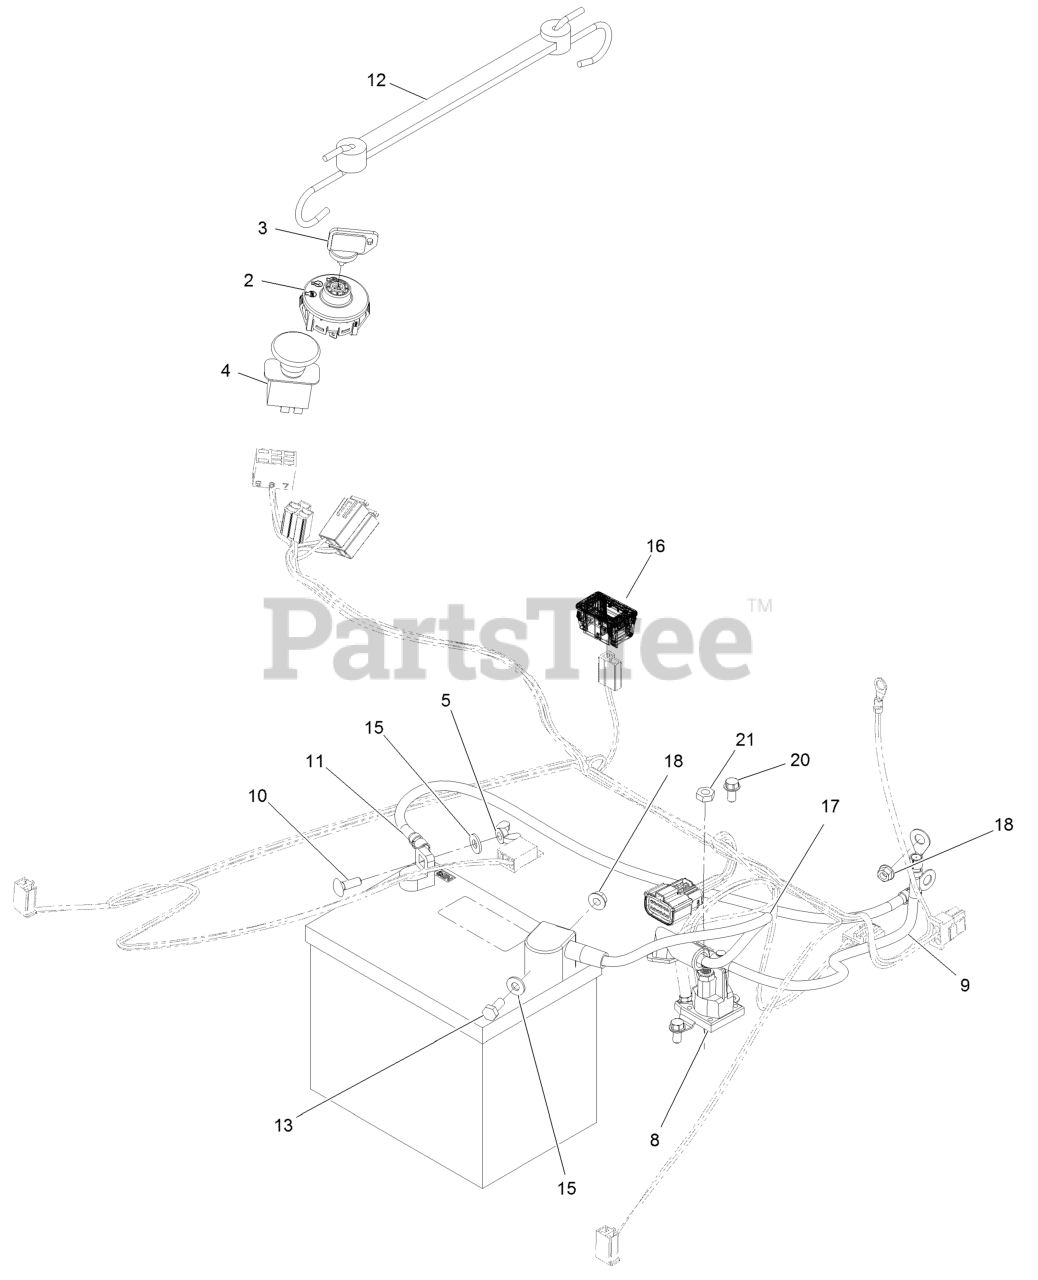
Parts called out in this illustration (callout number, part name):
3	KEY-IGNITION
4	SWITCH-PTO
5	NUT-WING
8	SOLENOID
9	CABLE-BATTERY, POSITIVE
10	BOLT-CARR
11	CABLE-BATTERY, BLACK
12	HOLDDOWN-BATTERY
13	SCREW-HH
15	WASHER-FLAT
16	HOURMETER
17	CABLE-BATTERY, RED
20	SCREW-HWH
21	NUT-JAM
